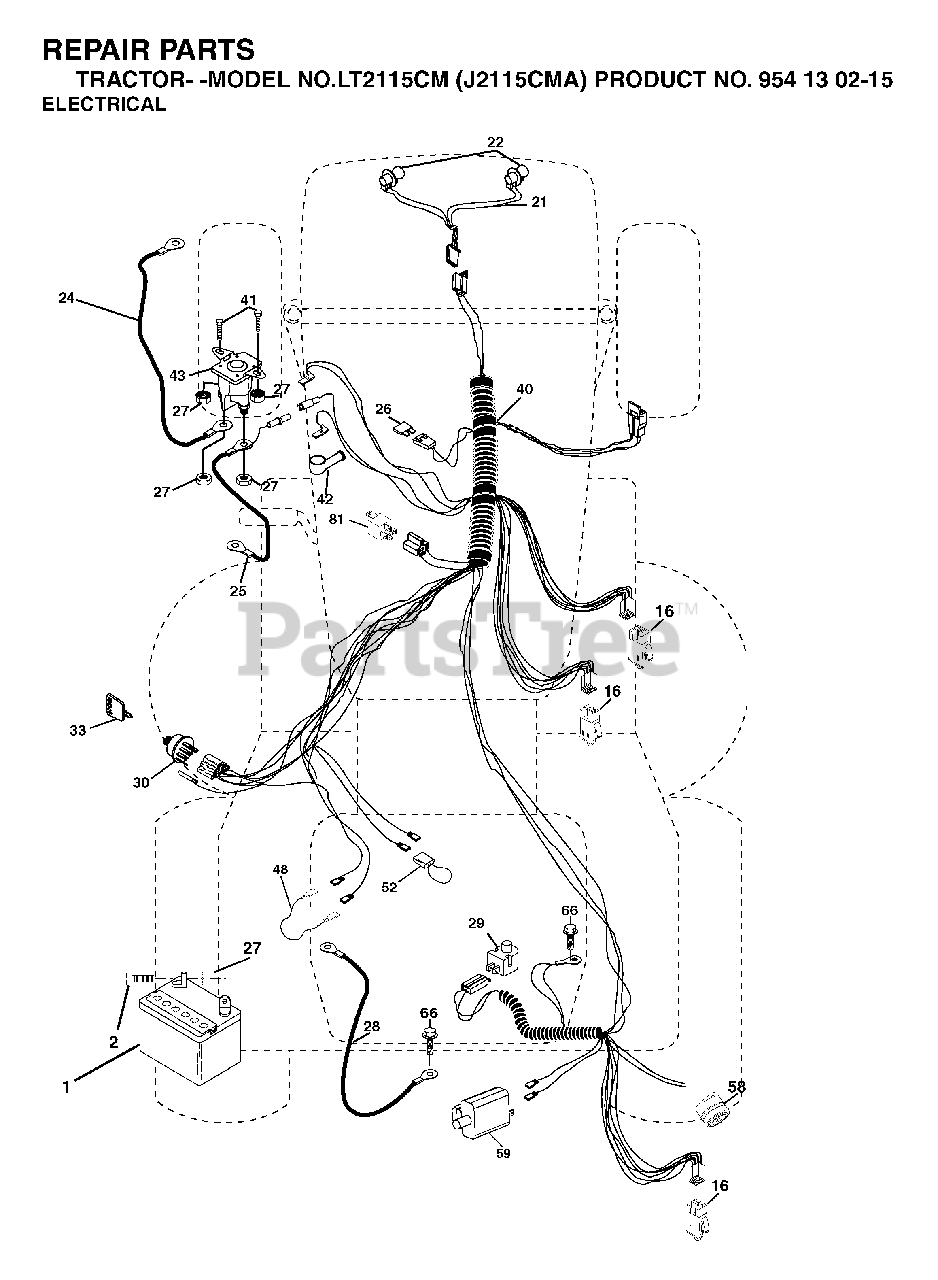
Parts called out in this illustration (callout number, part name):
1	BATTERY 12V .35 AMP
16	SWITCH INTERLOOK PUSH-IN
21	HARNESS.W/LIGHT SOCKET
22	LIGHTBULB
24	BATTERY CABLE GT
25	CABLE BATTERY
26	FUSE 20AMP
27	NUT
28	CABLE GROUND
29	SWITCH SEAT
30	IGNITION SWITCH
33	KEY MLD GEN DELTA
42	TERMINAL COVER
43	SOLENOID
52	WIRE PROTECTION LOOP
58	BUZZER
81	RELAY.ASSY.T
